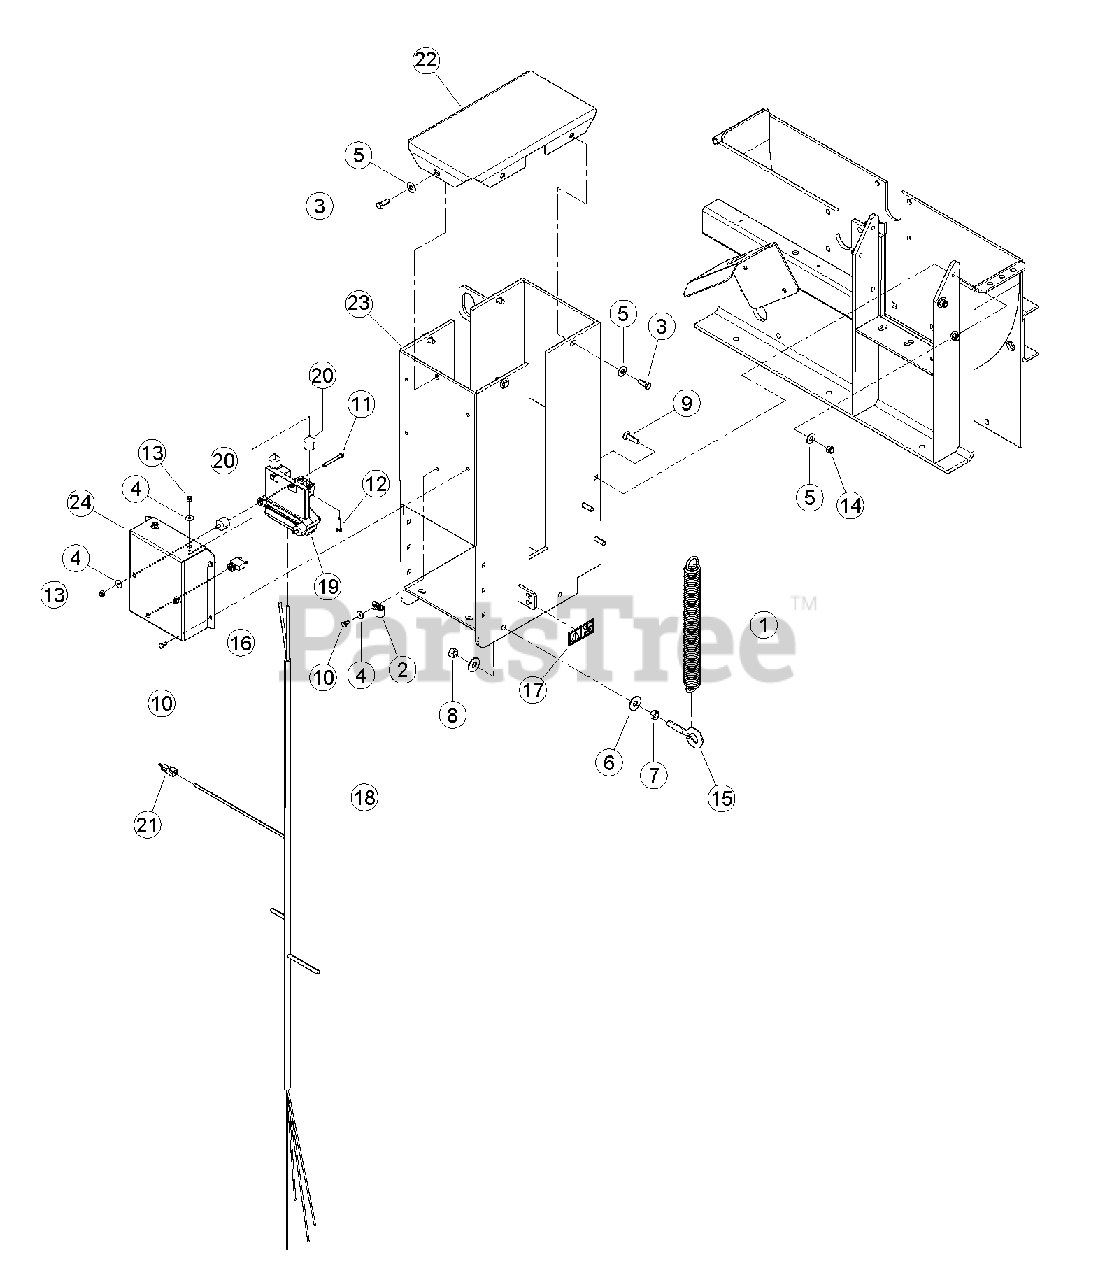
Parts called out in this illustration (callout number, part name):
1	SPRING, EXTENSION
2	CLAMP, 9/16" COATED
3	BOLT, 3/8 X 1 HEX HD GR5 ZP
4	WASHER, 1/4 FLAT ZP
5	WASHER, 3/8 FLAT ZP
6	WASHER, 1/2 FLAT ZP
7	NUT, 1/2 HEX NC ZP
8	NUT, 1/2 CENTERLOCK GRB ZP
9	BOLT, 3/8 X 1-1/2 CRG GR5 NC ZP
10	BOLT, 1/4 X 1/2 HEX HD GR5 ZP
11	BOLT, 1/4 X 2-1/4 HEX HD GR5 ZP
12	BOLT, 1/4 X 1-1/4 HEX HD GR5 ZP
13	NUT, 1/4 NE NYLOCK ZP
14	NUT, 3/8 NE NYLOCK ZP
15	EYEBOLT, 1/2 X 2 ZP
16	CIRCUIT BREAKER, 10 AMP RESETTABLE
17	DECAL, CRUSHING ISO
18	HARNESS, 9" PTO PLUS 1 CONTROLLER
19	CONTROLLER, PLUS 1 CHIPPER
20	BUMPER, 1" OD W/1/4" STUD
21	PLUG, JUMPER HARNESS
22	ENCLOSURE, PLUS 1 MOUNT
23	WELDMENT, TOP ROLLER COVER
24	WELDMENT, ROLLER SUPPORT
